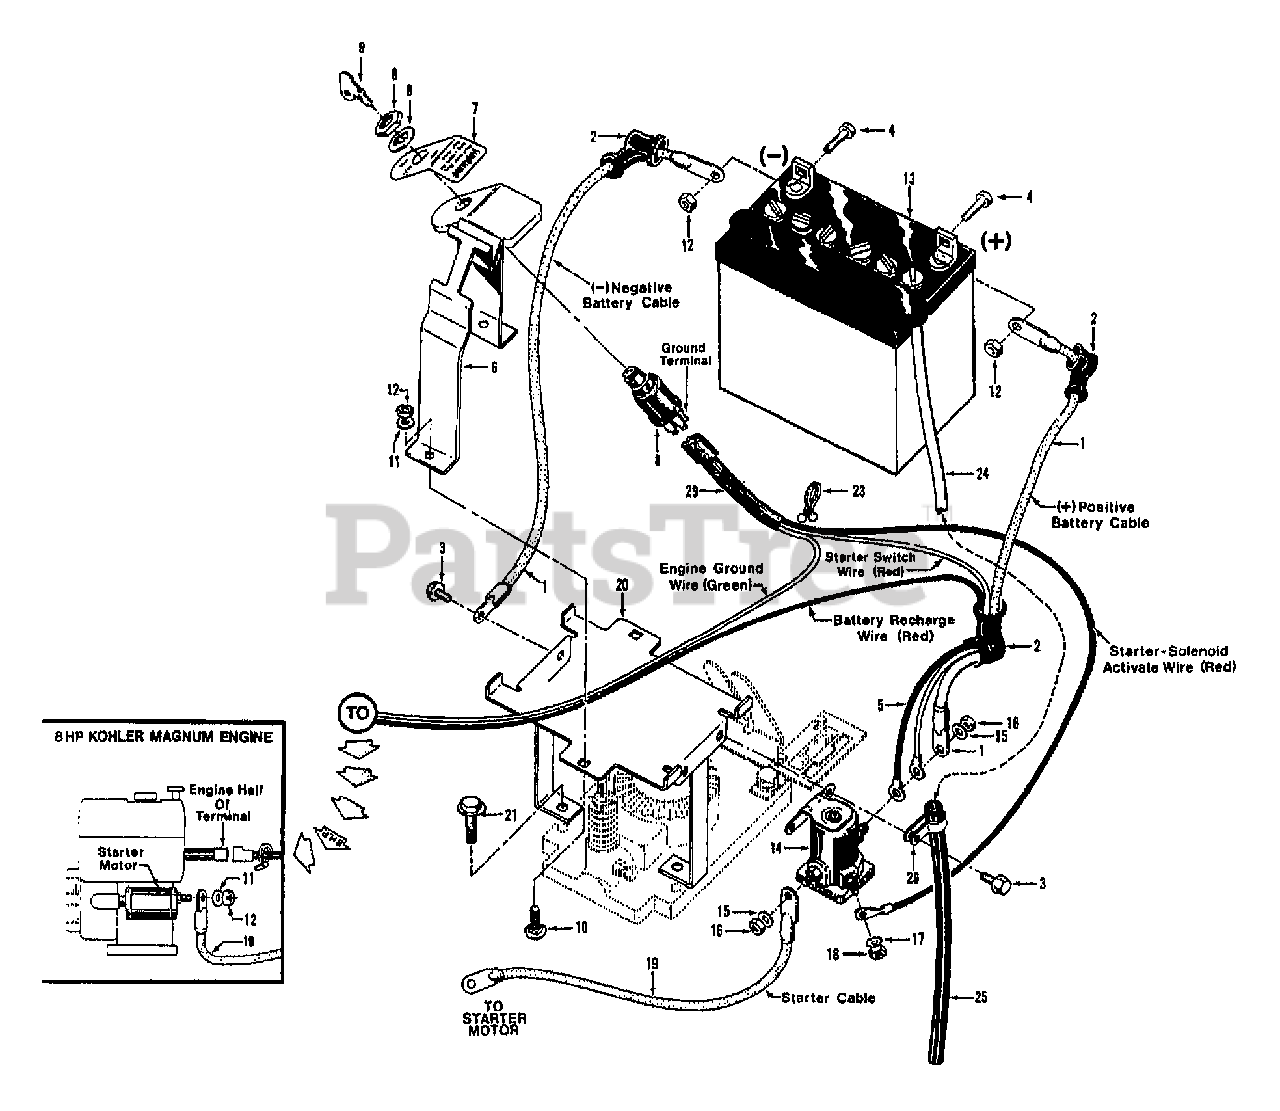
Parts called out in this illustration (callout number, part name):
1	CABLE-BATTERY 10"
2	BOOT-BATTERY CABLE
3	SCR-HWH 1/4-20 X .5 STH
4	SCR-HH 1/4-20X.625
5	NOT USED WITH 8HP KOHLER ENGINE
6	KEYSWITCH W/DECAL
7	DECAL-KEYSWITCH TILLER
8	KEYSWITCH W/KEYS
9	KEYS(1 PAIR) FOR SWITCH
10	SCR-CARR 1/4-20X1.25
11	WASHER-LK .25 ZP
12	NUT-HEX 1/4-20 ZP
13	BATTERY-12 VOLT HORSE
14	KIT-SOL W/HDW
15	WASHER-LK .312 ZP
16	NUT-HEX 5/16-24
17	WASHER-EXTERNAL TOOTH 1
18	NUT-HH M10-32X.125
19	CABLE-BATTERY 12"
20	BRKT-BATTERY OPC BLACK
21	SCR-HFLK 3/8-16X1.50
23	TIE-TWIST LOCK
24	TUBE-VENT BATTERY/HSE
25	TUBING-RUBBER
26	CLAMP
29	HARNESS-WIRE 3.5
